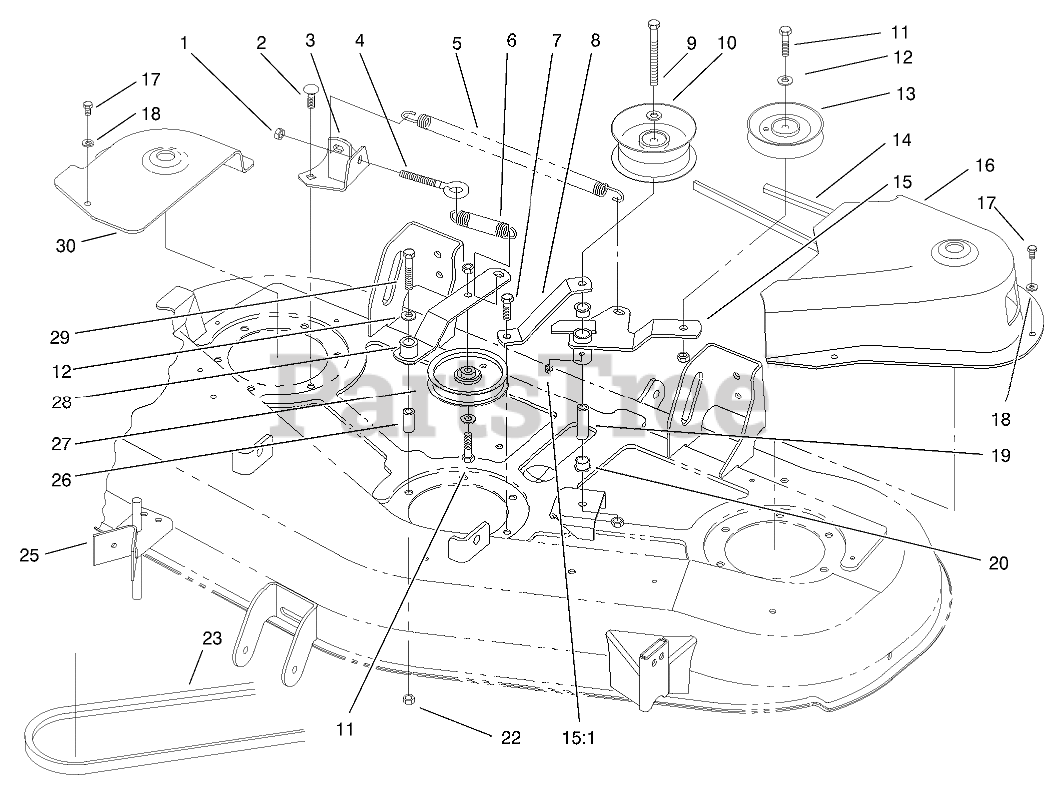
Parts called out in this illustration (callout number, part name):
1	NUT-LOCK, NI
2	SCREW-CARR
3	BRACKET-SPRING
4	BOLT-EYE
5	SPRING-EXTENSION
6	SPRING-EXTENSION
7	SCREW-HH
8	STRAP-SUPPORT
9	SCREW-HH
10	PULLEY-IDLER
11	SCREW-HH
12	WASHER-FLAT
13	PULLEY-IDLER
14	V-BELT
15	IDLER ARM ASSEMBLY
15:1	FITTING-GREASE
16	COVER-BELT, LH
17	SCREW-HWH
18	WASHER-FLAT
19	SPACER
20	BUSHING
22	NUT-HF
23	BELT - V
25	DECK UPSTOP ASM
26	SLEEVE
27	PULLEY-IDLER
28	IDLER ARM ASM
29	SCREW-HH
30	COVER - BELT, RH
